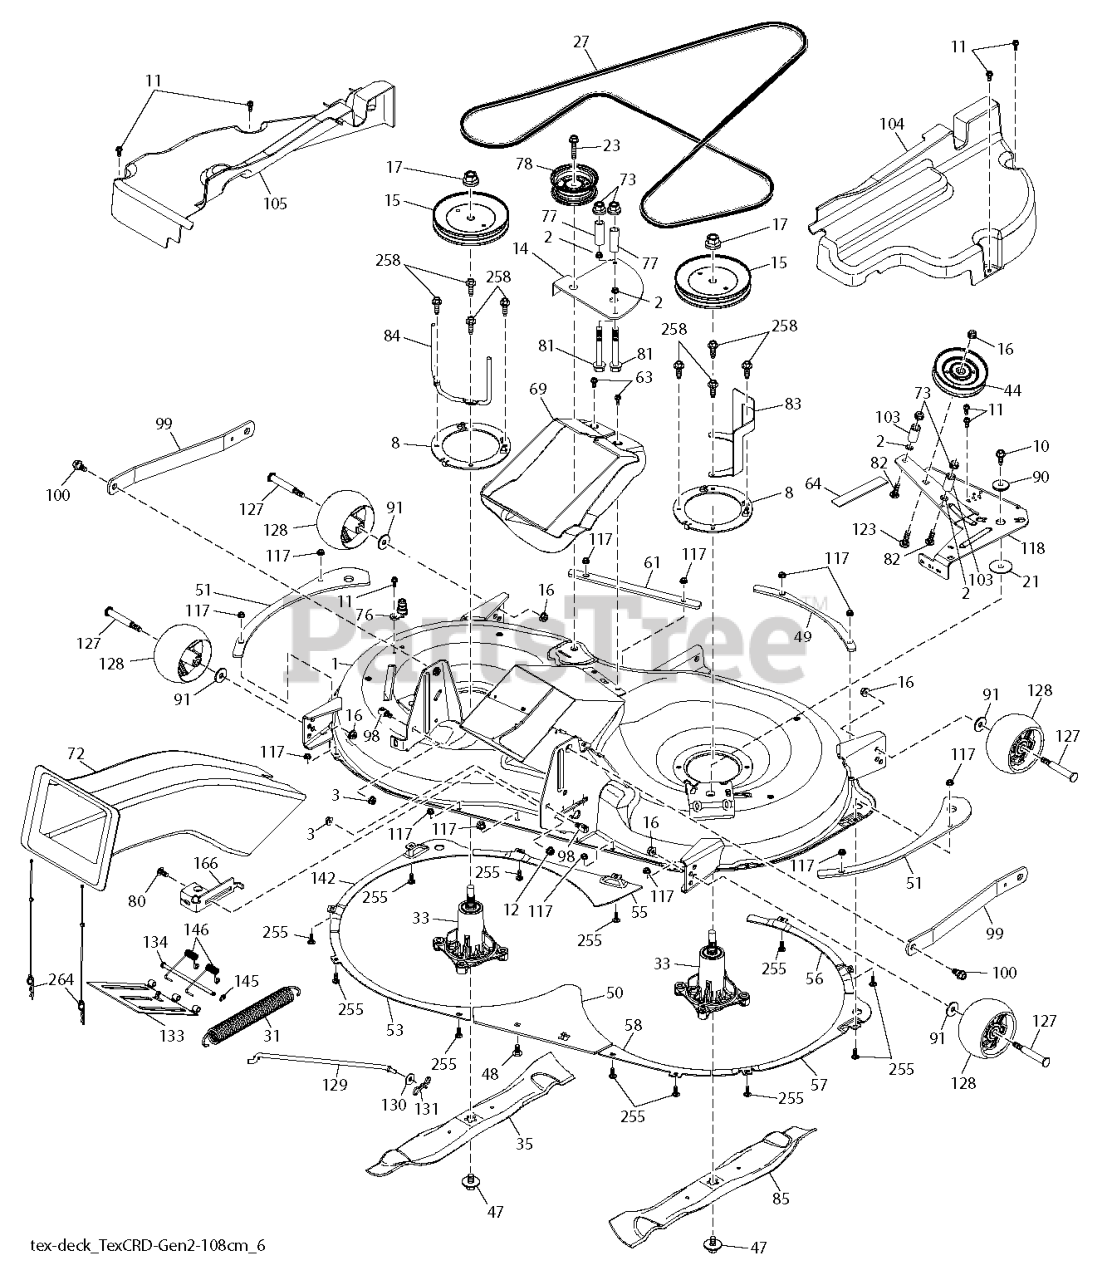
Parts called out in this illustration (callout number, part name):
2	PALNUT 1/4
3	GSPW Nuts
10	SCREW 3/8-16X1
11	SCREW.1/4-20X5/8
12	NUT HEXAGON FLANGE 5/16-18 ST
15	PULLEY.MANDREL.5.438.P
16	NUT LOCK FLG 3/8-16 UNC
21	WASHER, WEAR LT (1 2)
23	BOLT;HEX_3/8-16 X 1.78.CLRZINC
31	SPRING.EXTENSION
33	Mandrels
44	PULLEY.V.IDLER
47	SCREW.SEMS.7/16-20X1.HEX.HEAD
63	HEX.WASHER.HEAD 1/4-20 X .65
64	VIBRATION PAD
72	Chutes
73	NUT FLG, NYLOCK, 1/4-20 GR G C
76	PORT.WASHOUT
77	SPACER.KEEPER
78	PULLEY.IDLER.48"PRIMARY
80	GSPW Bolts
81	BOLT.HEX.FINISHED.1/4-20
82	BOLT.RDHD.SHRT.NK.1/4-20X1-1/2
84	KEEPER.BLT.PNT.MNDRL.PULL.6.25
90	SPACER.RETAINER
98	STUD.W/"D"ANTI-ROTATION
100	BOLT.SHOULDER
117	NUT T
118	ARMS
123	GSPW Bolts
128	WHEEL.GAUGE.RALLY
129	ROD ROD. SWAY CRD GEN II
131	PIN.COTTER.5/16.BOW TI
145	E-RING.5/16"
146	SPRING SPRING: EZ MULCH DOOR
255	BOLT CUP HEAD SQUARE NECK BOLT
258	BOLT.HEX.WASHR.HED.313-18X1.19
